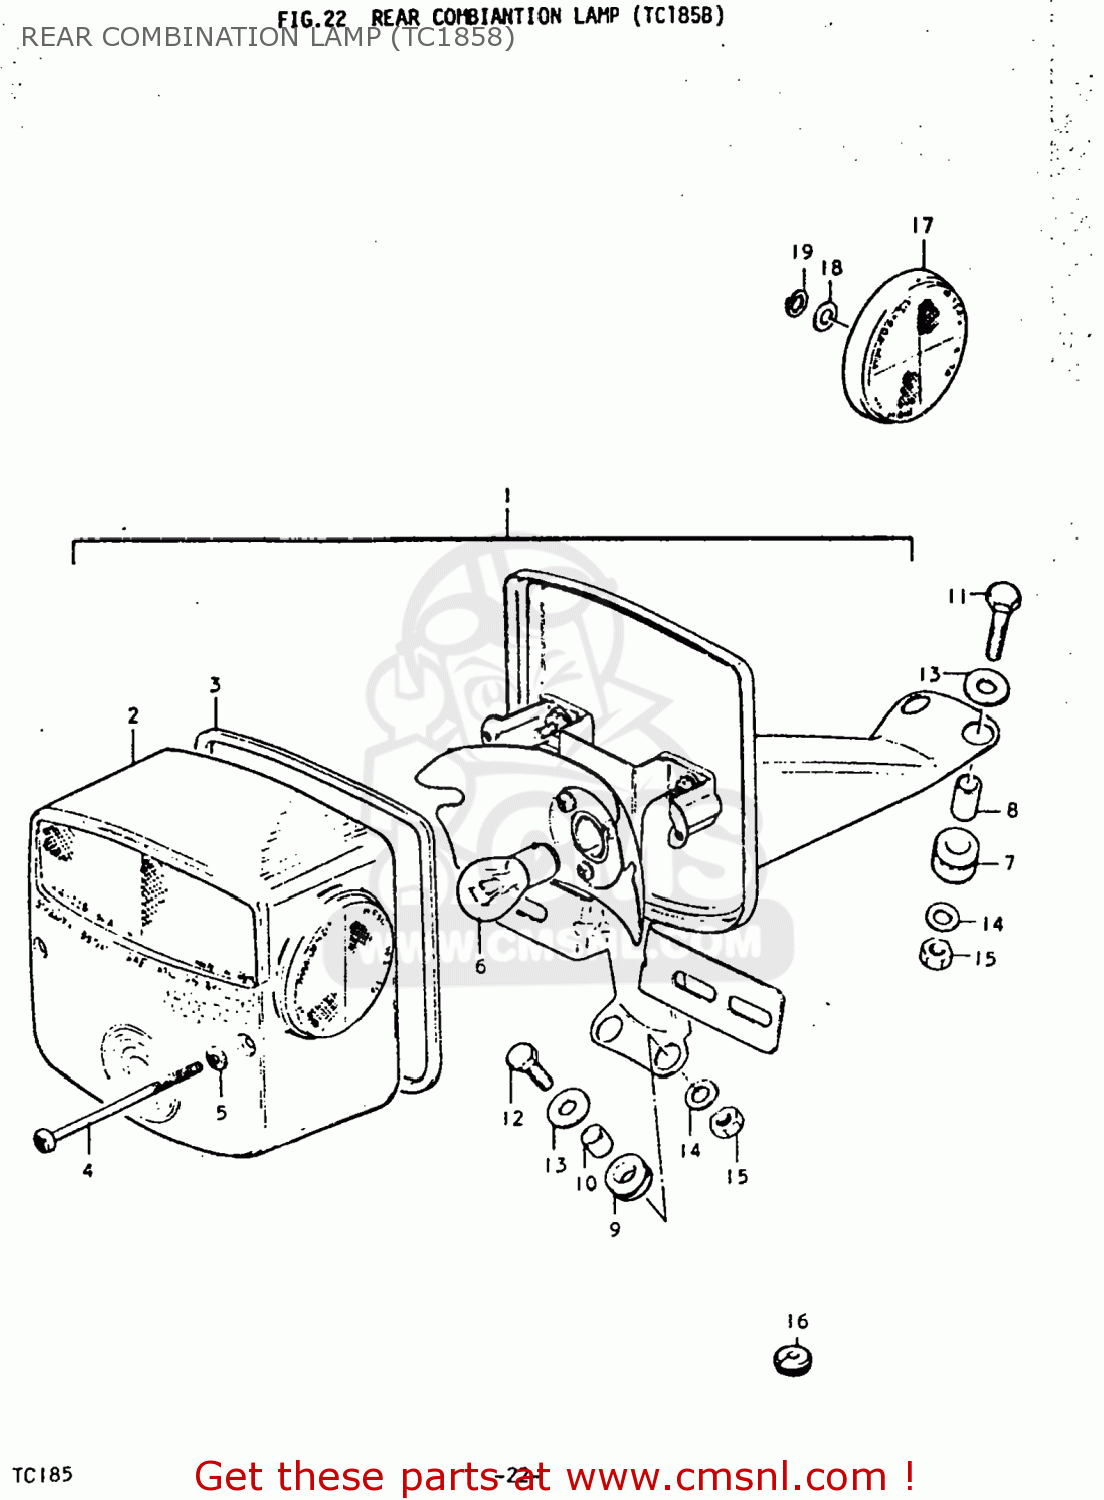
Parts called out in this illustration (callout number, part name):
1	LAMP ASSEMBLY,REAR COMBINATION
2	LENS,REAR COMBINATION LAMP
3	GASKET (NAS)
4	SCREW
5	GASKET (NAS)
6	BULB(12V23W)
7	CUSHION
8	SPACER,REAR COMBINATION LAMP
9	CUSHION
10	SPACER,REAR COMBINATION LAMP
11	BOLT
12	BOLT
13	WASHER (6.5X20X1.2)
14	LOCK WASHER
15	NUT
16	GROMMET
17	REFLEX REFLECTOR,FR
18	WASHER
19	LOCK WASHER
